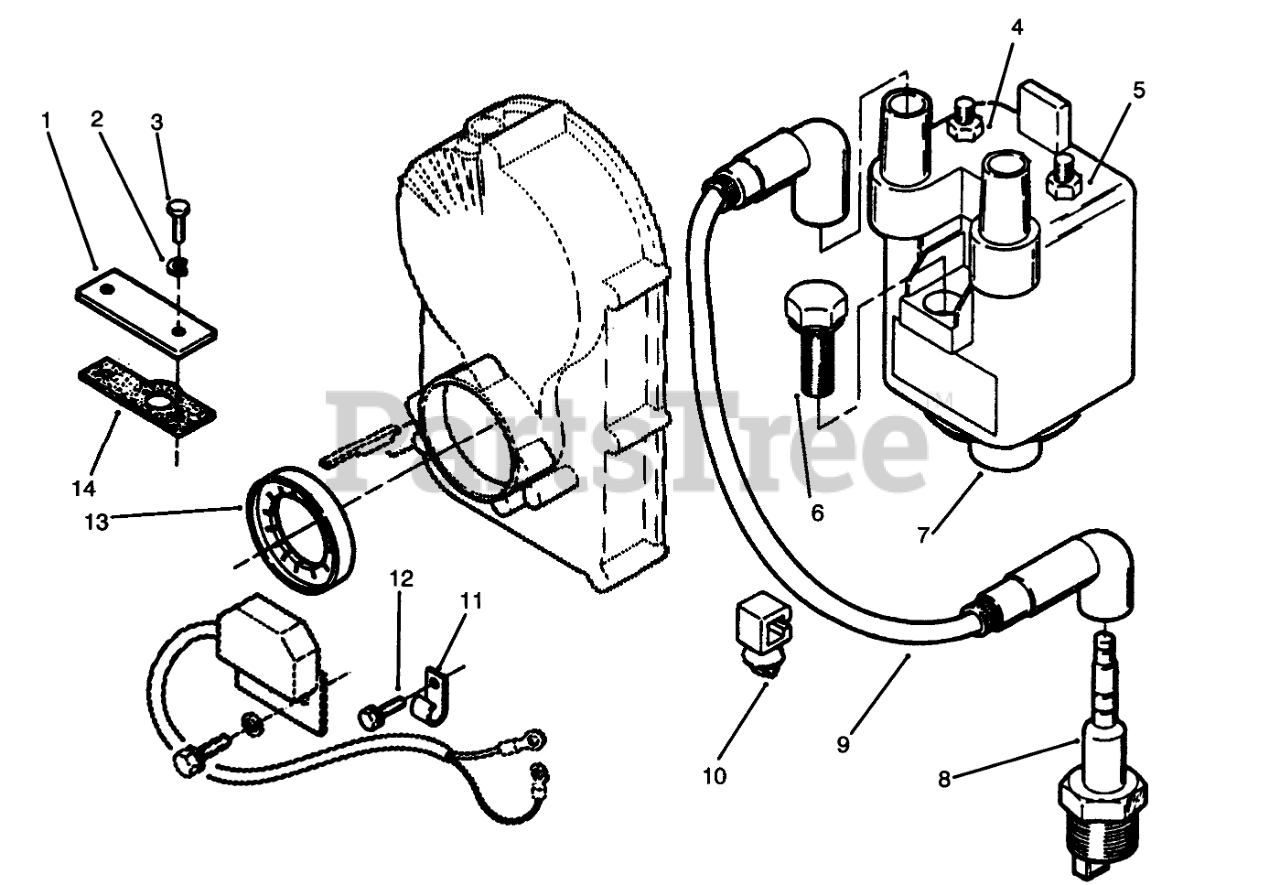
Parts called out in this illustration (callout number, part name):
1	PLATE-COVER
2	WASHER-FLAT
3	SCREW - CAP HEX HEAD
4	Nut
5	Nut
6	HEX-HEAD CAP SCREW
7	Coil-Battery Ignition (Incl. Ref. #4-5)
8	SPARK PLUG
9	Wire-Plug
10	WIRE ROUTING CLIP
11	Clip
12	SCREW-HH
13	ROTOR-IGNITION
14	Gasket-Plate
